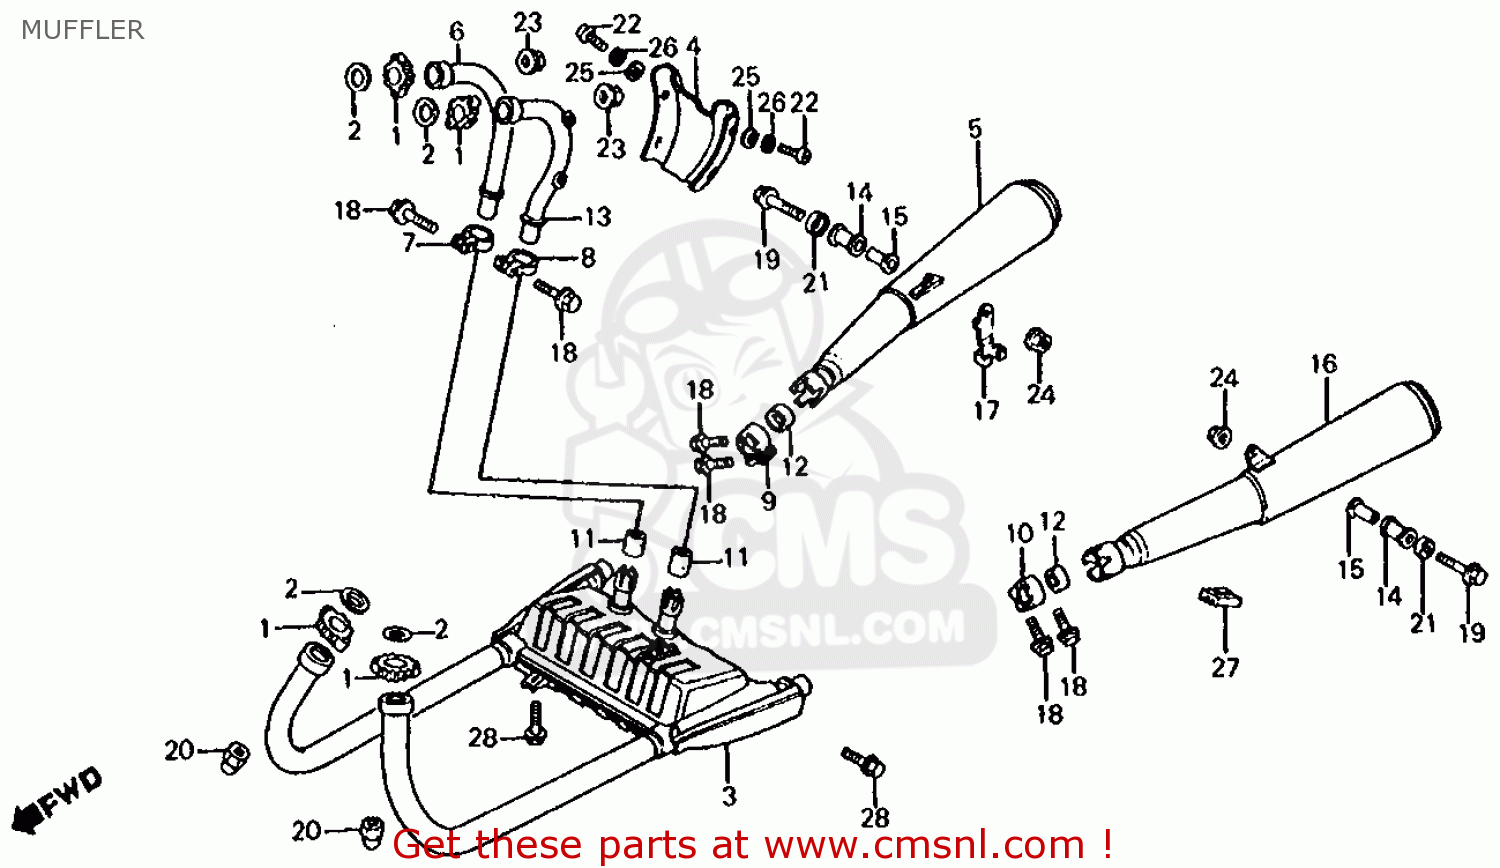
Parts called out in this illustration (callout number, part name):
1	JOINT,EX.PIPE
2	GASKET,EXH.PIPE (NAS)
3	CHBR.COMP EXH
4	PROTECT,RR.EXPIPE
5	MUFFLER COMP.,R.
6	PIPE,R.RR.EX.
7	BAND,EX.PIPE
8	BAND,L.EX.PIPE
9	BAND,R,MUFFLER
10	BAND,L.MUFFLER
11	PACKING,EX. (NAS)
12	PACKING,MUFFLER (NAS)
13	PIPE,L.RR.EX.
14	RUB,MUF.MOUNTING
15	COLLAR,MUFF MOUNT
16	MUFFLER COMP.,L.
17	GUIDE,DRAIN PIPE
18	BOLT,FLANGE,8X37
19	BOLT,FLANGE,8X45
20	NUT,CAP,6MM
21	WASHER,SPECIAL,
22	SCREW,PAN,6X8
25	WASHER PLAIN 6MM
26	WASHER,SPRING,6MM
27	STOPPER RUBBER C
28	BOLT,FLANGE,6X18
